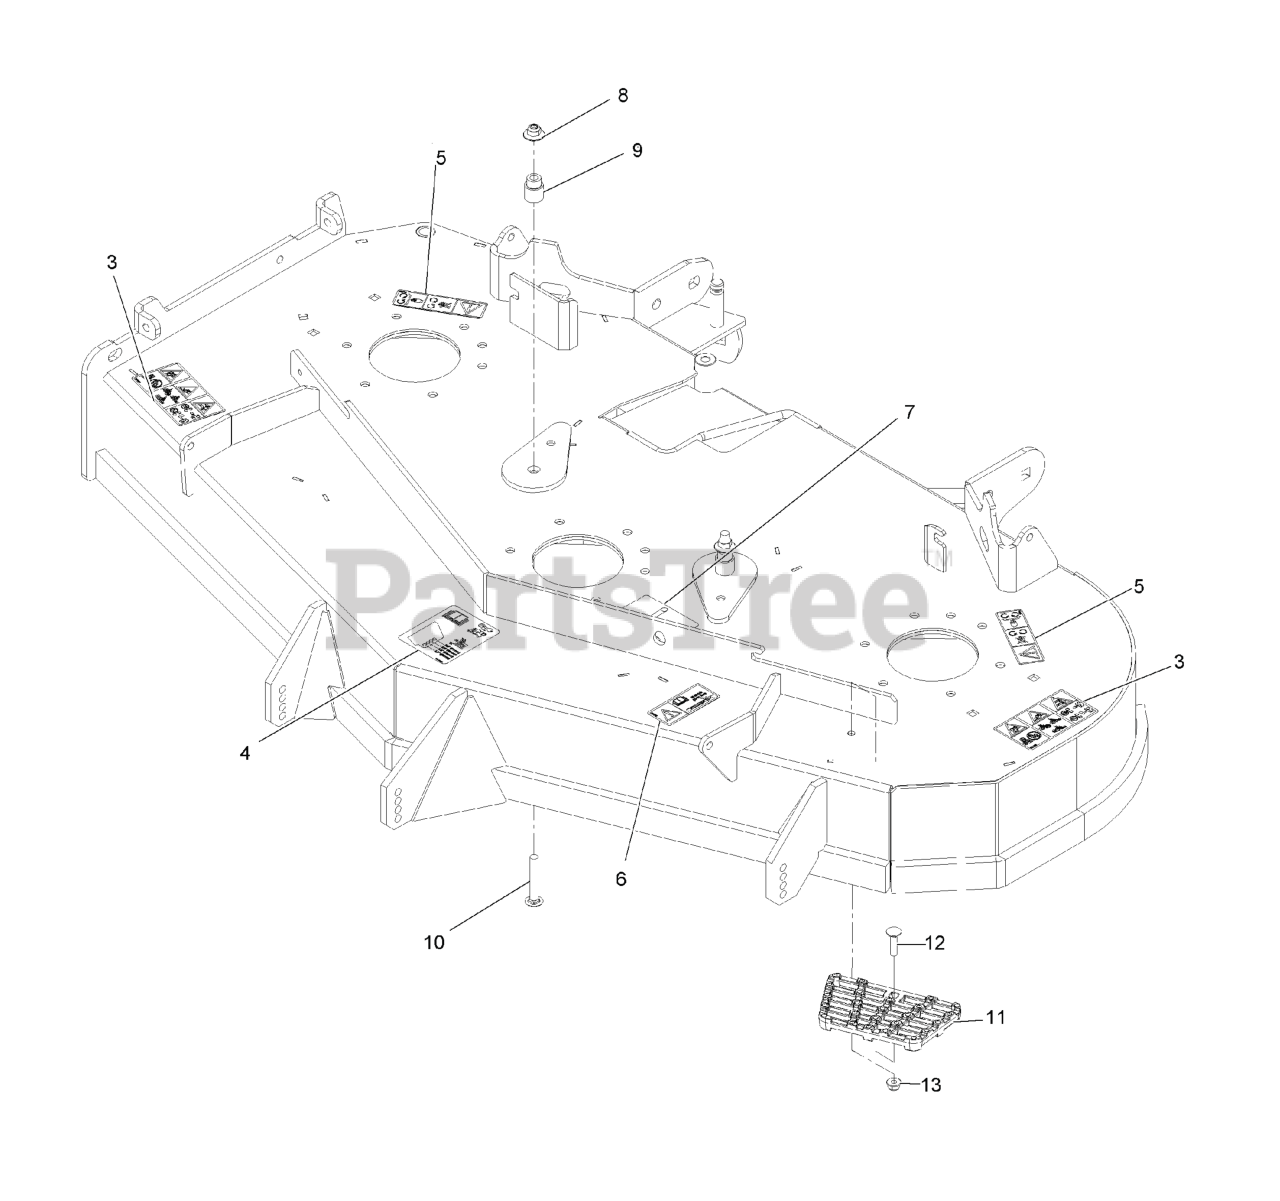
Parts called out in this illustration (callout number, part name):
3	DECAL-DANGER THROWN OBJECTS
4	DECAL-ROLLER, ANTI-SCALP
5	DECAL-COVER, MISSING
6	DECAL-TORQUE, BOLT
7	DECAL-BELT ROUTING
8	Nut-Nyloc 3/8-16 Flg
9	BUSHING-IDLER
10	SCREW-CARR
11	STEP-DECK
12	Bolt-Carriage 5/16-18 X 1 1/4
13	NUT-HF, NI
